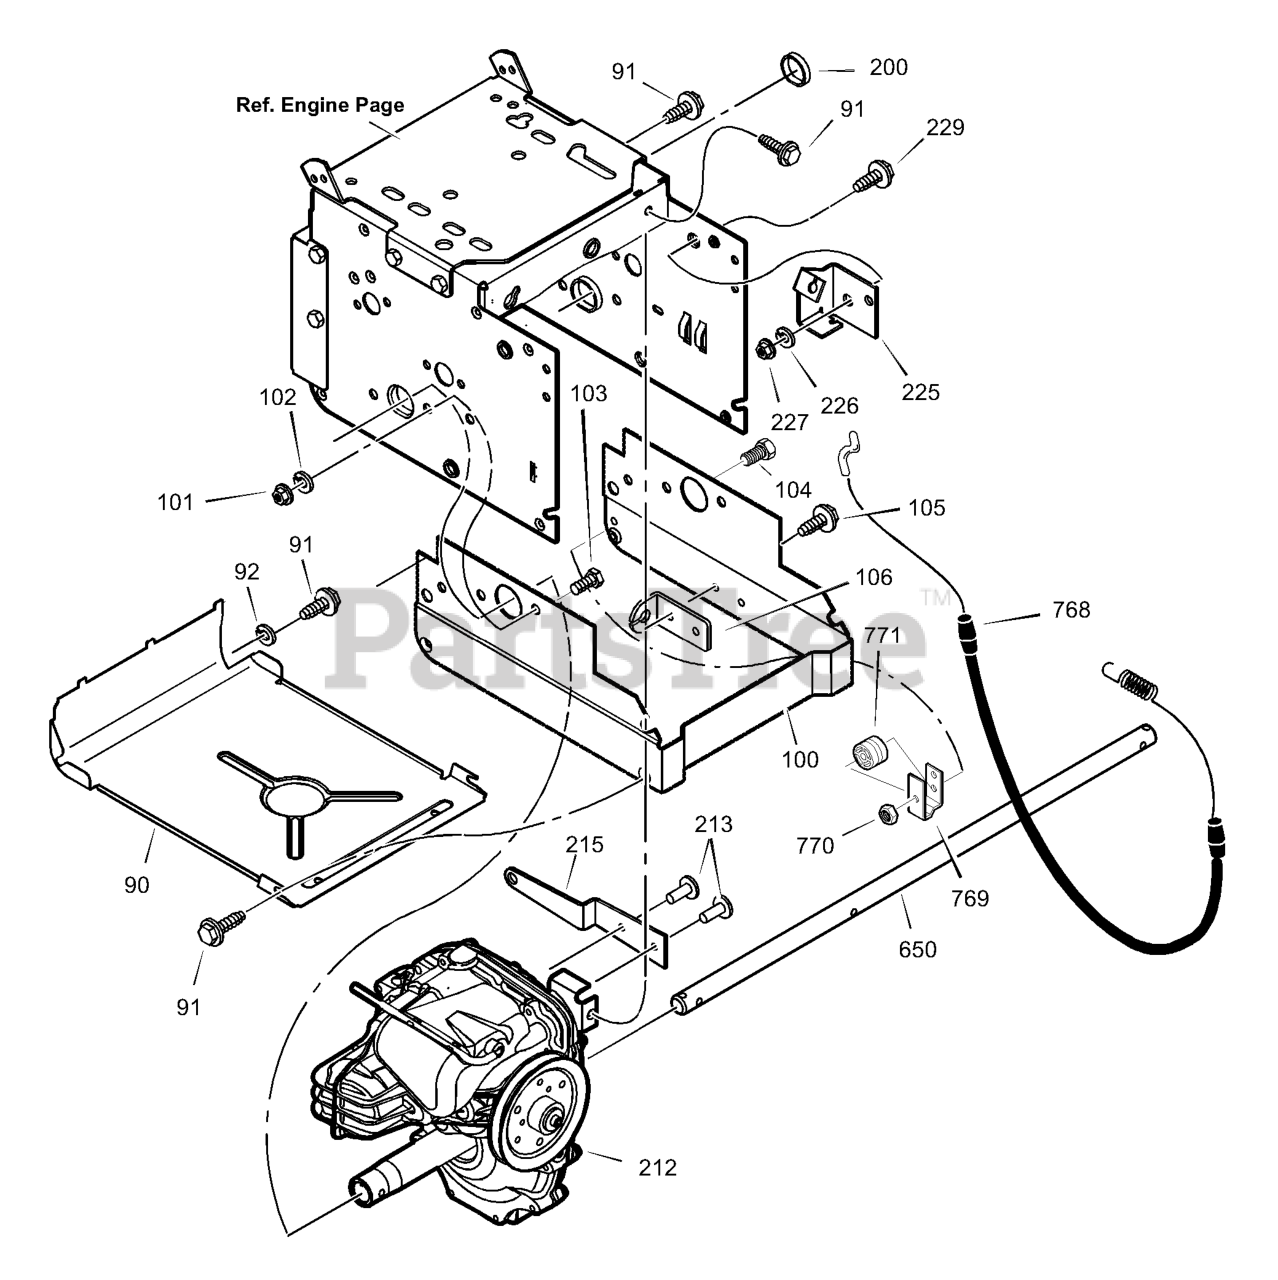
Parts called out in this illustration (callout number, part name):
90	COVER, BOTTOM
91	SCREW, 1/4-20 X 0.62
92	WASHER
100	FRAME, EXTENSION - HYDRO
102	WASHER
104	BOLT
105	SCREW
106	BRACKET, CABLE
200	PLUG, HEYCO
212	Transmission, Hydro *
213	RIVET, BLIND
215	ARM, CONTROL EXTENSION
225	BRACKET, DRIVE CABLE
226	WASHER
227	NUT, HEX JAM - 3/8-16
229	SCREW
650	AXLE, WHEEL
768	CABLE, HYDRO DRIVE
769	BRACKET, CABLE SPOOL YZ
770	NUT
771	SPOOL, CABLE
